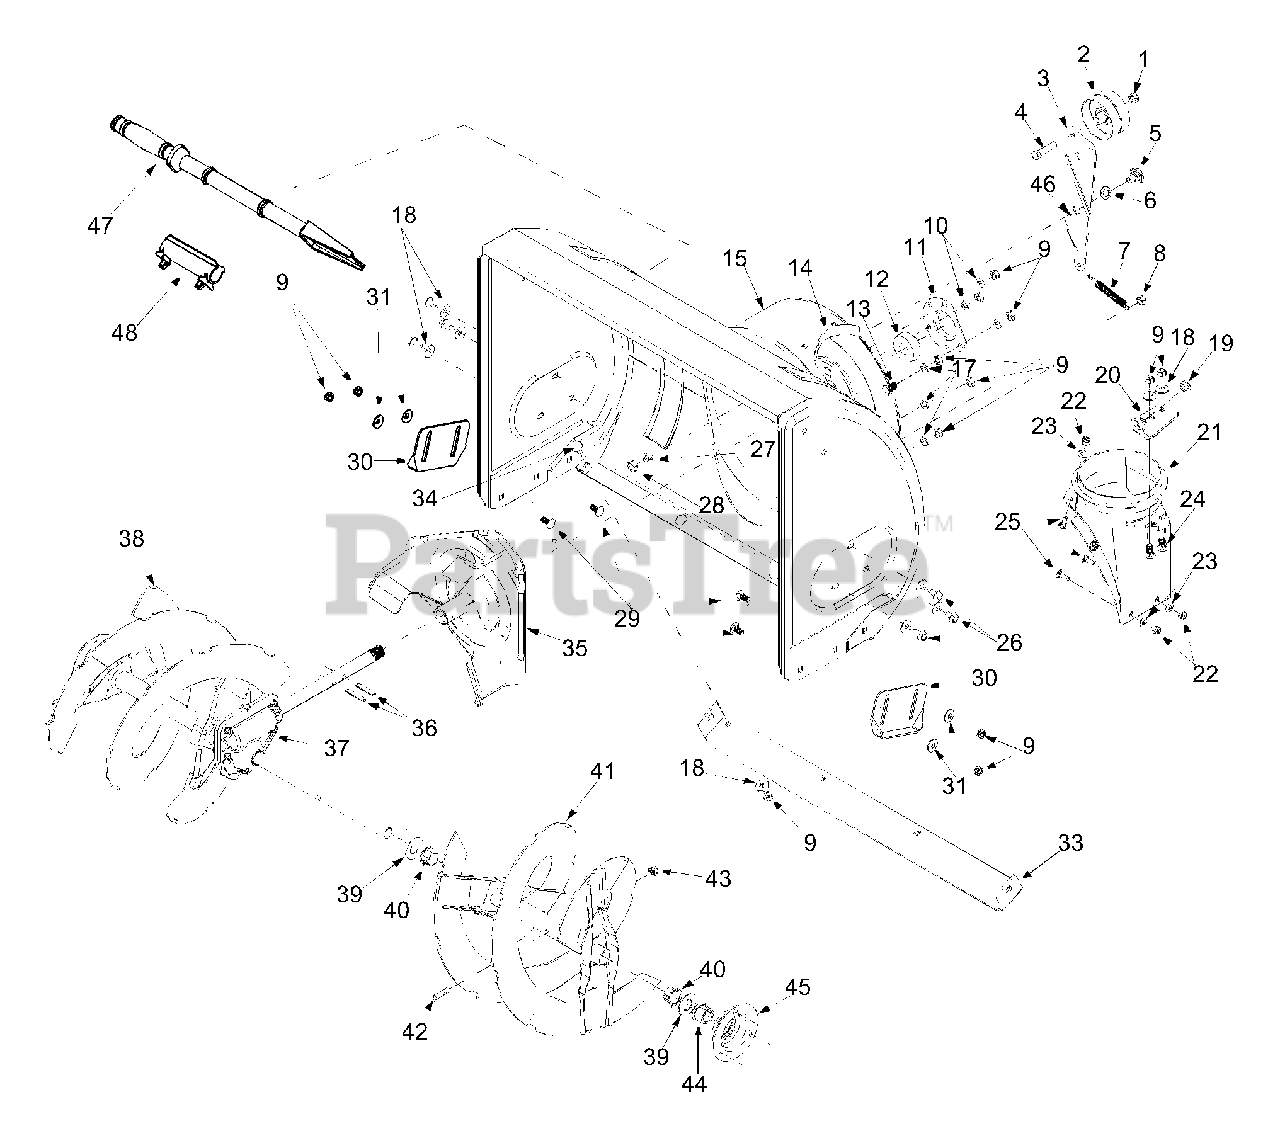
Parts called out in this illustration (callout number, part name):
1	Lock Jam Nut 3/8-24
2	Flat Idler
4	Hex Cap Screw 3/8-24 x 1.50
5	Shoulder Screw
6	Flat Washer
7	Extension Spring
8	Hex Nut 5/16-18
9	Hex Nut 5/16-18
10	Lock Washer 5/16
11	Housing
12	Ball Bearing
13	Carriage Bolt 5/16-18
19	Bushing
21	Chute Adapter
22	Hex Lock Nut 1/4-20
23	Flat Washer
24	Carriage Bolt
25	Carriage Screw 1/4-20 x .75
26	Hex Washer Screw 5/16-12 x .75
27	Lock Washer 3/8
28	Hex Nut 3/8-16
29	Carriage Bolt 5/16-18 x .75
31	Bell Washer
37	26" Gear Assembly
39	Flat Washer
40	Flange Bushing
43	Lock Nut 5/16-18
44	Hex Flange Bearing
46	Grease
47	Chute Clean-out Tool
48	Mount, Chute Clean-out Tool
